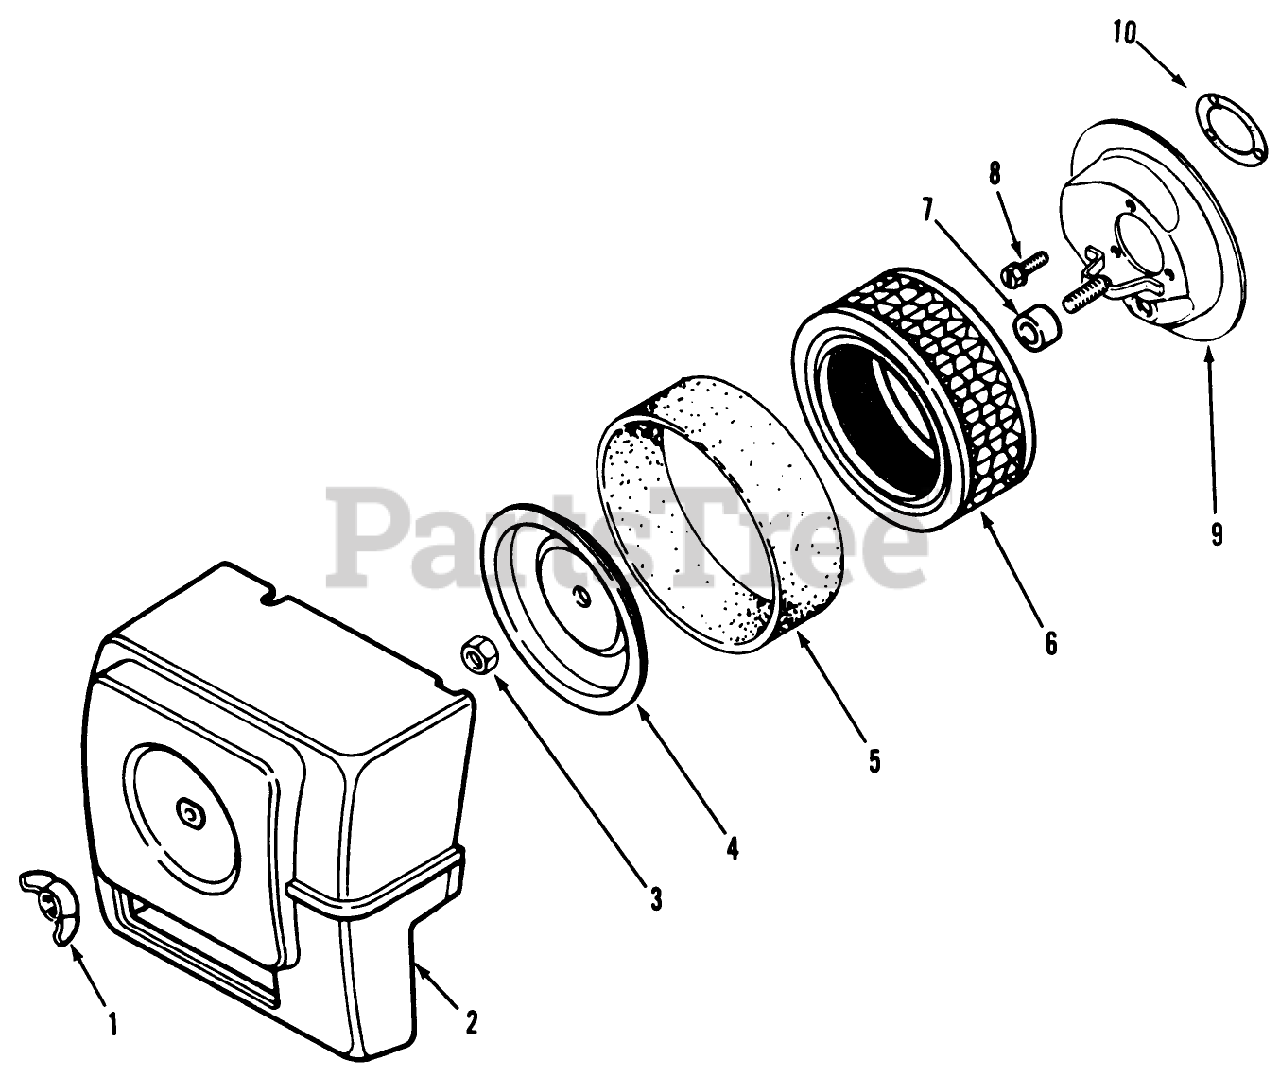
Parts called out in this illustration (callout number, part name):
1	KOHLER X-276-7
2	KOHLER 47-096-10
3	KOHLER 41-100-04
4	KOHLER 52-082-04
5	KOHLER45-083-01
6	KOHLER 45-083-02
7	KOHLER 231032
8	KOHLER X-67-65
9	KOHLER 47-094-20
10	KOHLER 45-041-07
